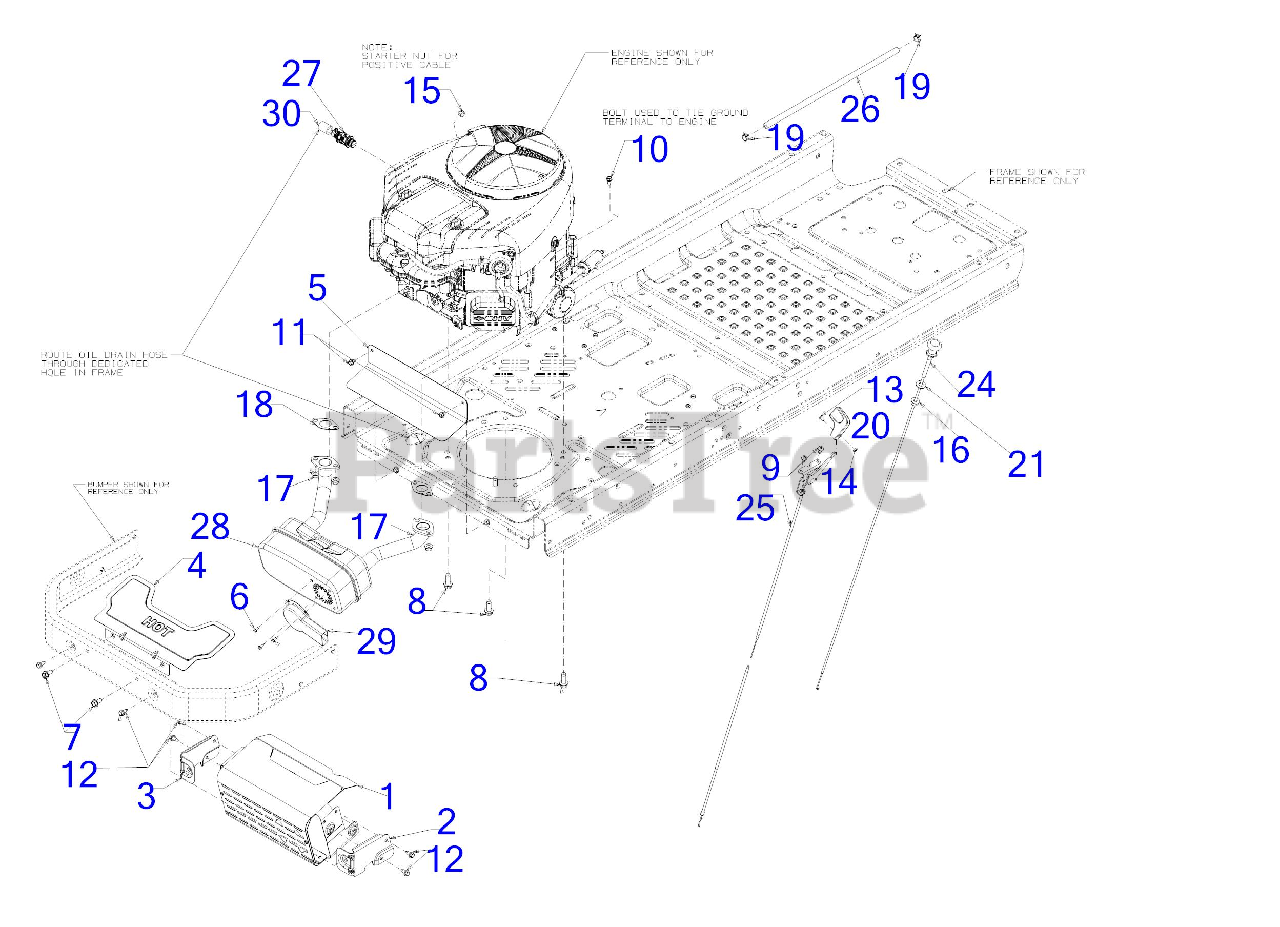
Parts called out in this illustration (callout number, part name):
5	LOWER HEAT SHIELD
6	HEX SCREW WASHER HD #8-18 x 0.500
7	SCREW 5/16-18 x .750
8	SCREW 3/8-16 x 1
9	SCREW 1/4-20 x .5
10	SCREW 1/4-20 X.500
11	SCREW 1/4-20 x .375
12	SCREW 1/4-20X.625
13	SCREW #8-32X.38 LG
14	HEX NUT 8-32
15	FLANGE LOCK NUT
16	HEX FLANGE NUT
17	HEX FLANGE NUT M8X
18	MUFFLER GASKET
19	HOSE CLAMP 1/20
20	THROTTLE CONTROL KNOB
21	FLAT WASHER
24	40.5" CHOKE CABLE
25	THROTTLE CABLE 41.5"
26	FUEL HOSE LOW PERMEATION
27	OIL DRAIN VALVE
28	EXHAUST MUFFLER(B&S)(TWIN)
29	EXHAUST DELECTOR
30	DRAIN HOSE 14''
